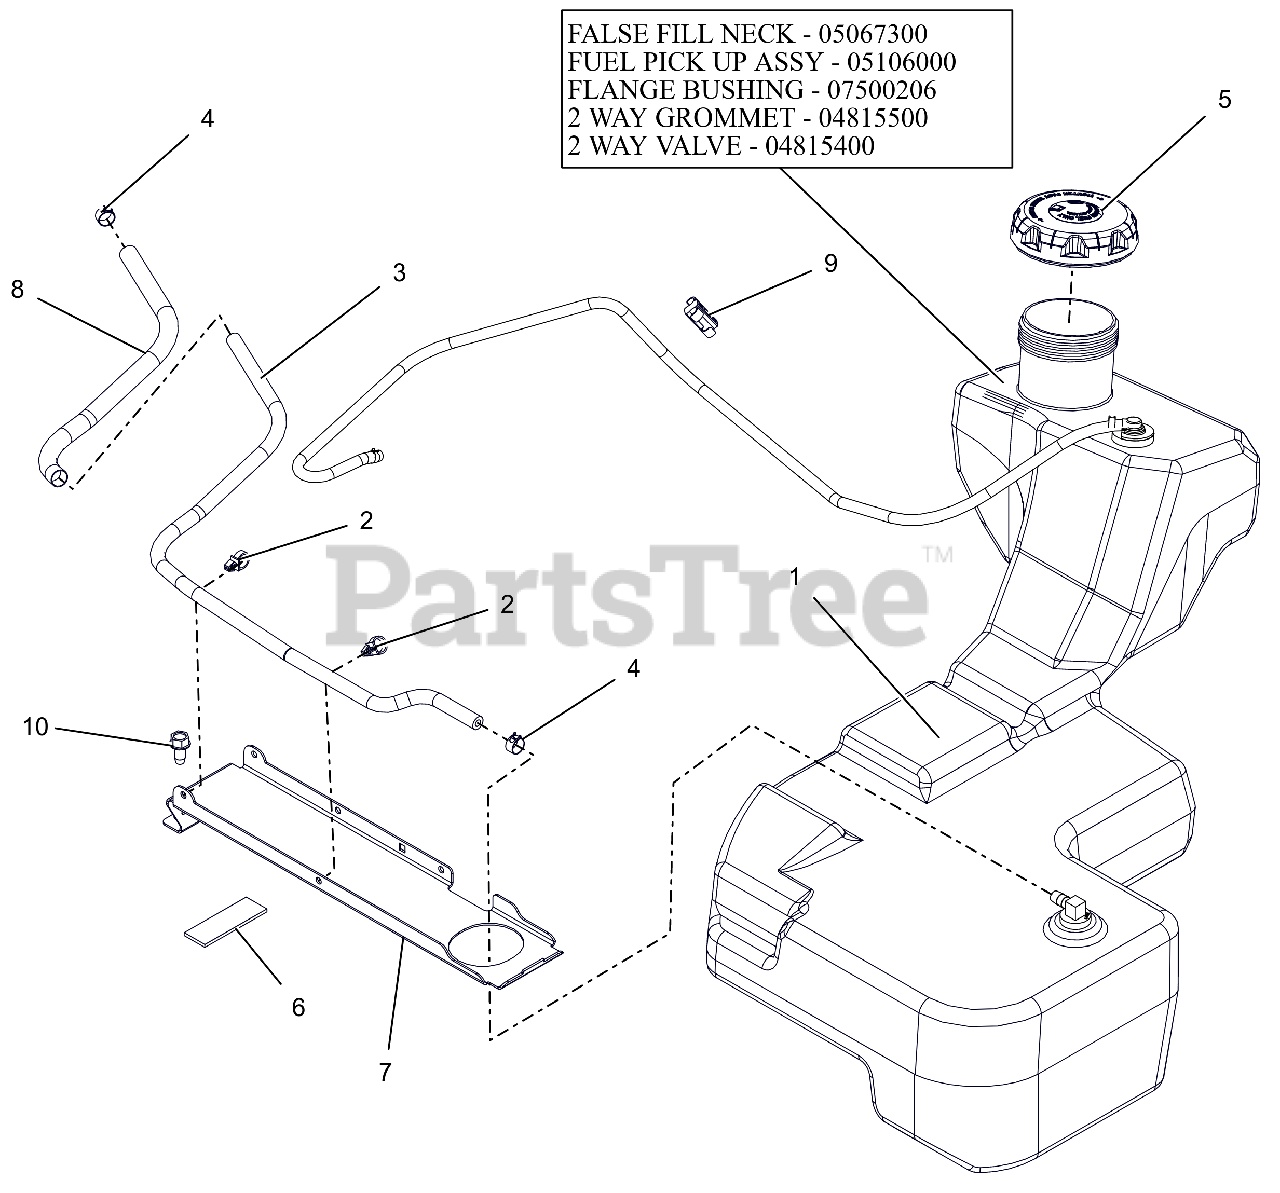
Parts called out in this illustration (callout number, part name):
1	ASSY, FUEL TANK-HD
1	INSERT, FUEL NECK FALSE FILL
1	ASM, HD FUEL PICK-UP
1	BSHG-FLG .375X1.062X.625 NITR
1	GROMMET, 2-WAY
1	VALVE, 2-WAY
2	ROUTING CLIP (1/2" ID)
3	HOSE, .25 LOW-PERM BULK GAS
4	CLAMP, FUEL LINE
5	CAP, FUEL VENTIN AUTOLOCK
6	PAD,RBR 1.0"X3.0" W/ADHESIVE
7	BRKT, FUEL TANK HOLD DOWN
8	SLEEVE, THERMAL 12"
9	CLIP, T, .38-.50
10	SCR,TAP .375-16X.75 HWH TR ZCC
